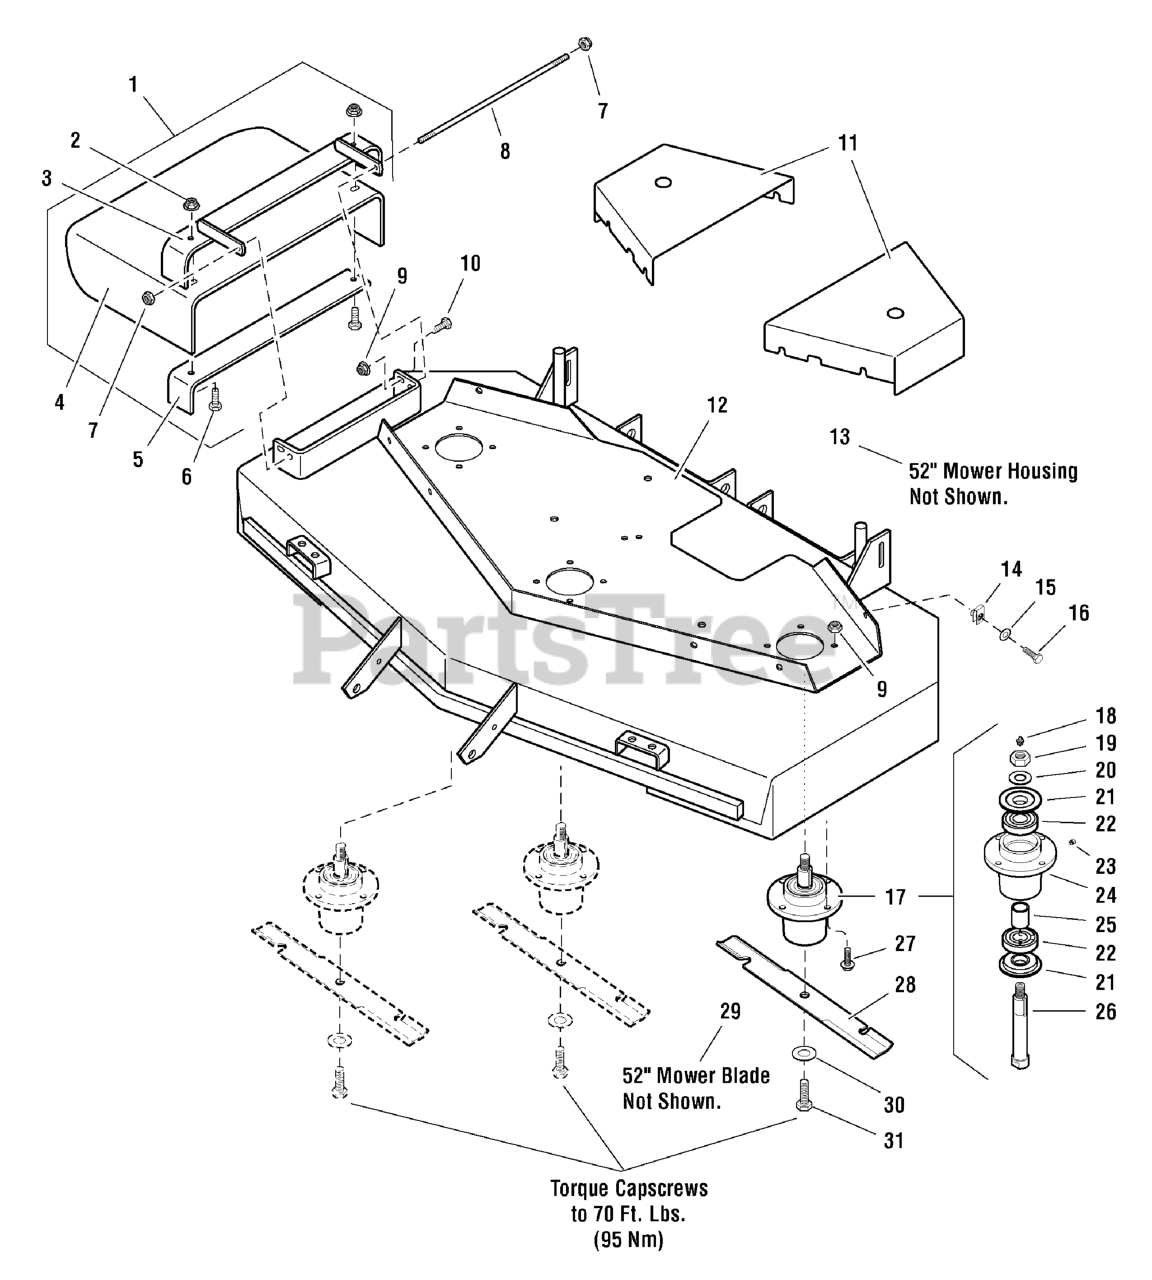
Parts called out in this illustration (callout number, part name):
1	RUBBER CHUTE ASSEMBLY, Complete
2	NUT, 3/8 - 16 HEX NYLOCK FLANGE
3	CHUTE FRAME
4	RUBBER CHUTE
5	CHUTE SUPPORT
6	BOLT, 3/8-16 X 1-1/4" GD5 CZ
7	NUT, 5/16-24 HEX NYLON LOCK
8	ROD, 5/16 X 13.75, TBE, CZ
9	NUT, 5/16-18 HEX NYLOCK FLANGE NUT
10	BOLT, 5/16-18 X 3/4 GD5
11	MOWER HOUSING GUARD
12	DECK SHELL W/DECALS, 48"
14	BODY CLIP, 5/16-18-7GA MATERIAL
15	WASHER, 5/16" SAE
16	BOLT, 5/16-18 X 3/4 GD5
17	SPINDLE, ASSM, ALUMINUM - 5.25
18	GREASE FITTING
19	NUT, 3/4-16 Hex
20	WASHER, 3/4 BELLEVILLE CL/ZC
21	TRASH SHIELD
22	BEARING, .98 X 2.44 X .67
23	FITTING, RELIEF, 1-5 PSI
24	HOUSING, SPINDLE
25	SPACER, 1.00 x 1.25 x 1.75
26	SPINDLE SHAFT
27	BOLT, Flange Head, 5/16-18 x 1-1/4
28	BLADE SET, 48 DECK (SET OF 3 BLADES)
29	MOWER BLADE, 18"
30	WASHER, 5/8" USS
31	BOLT, 5/8-11 X 1-3/4 GD8
